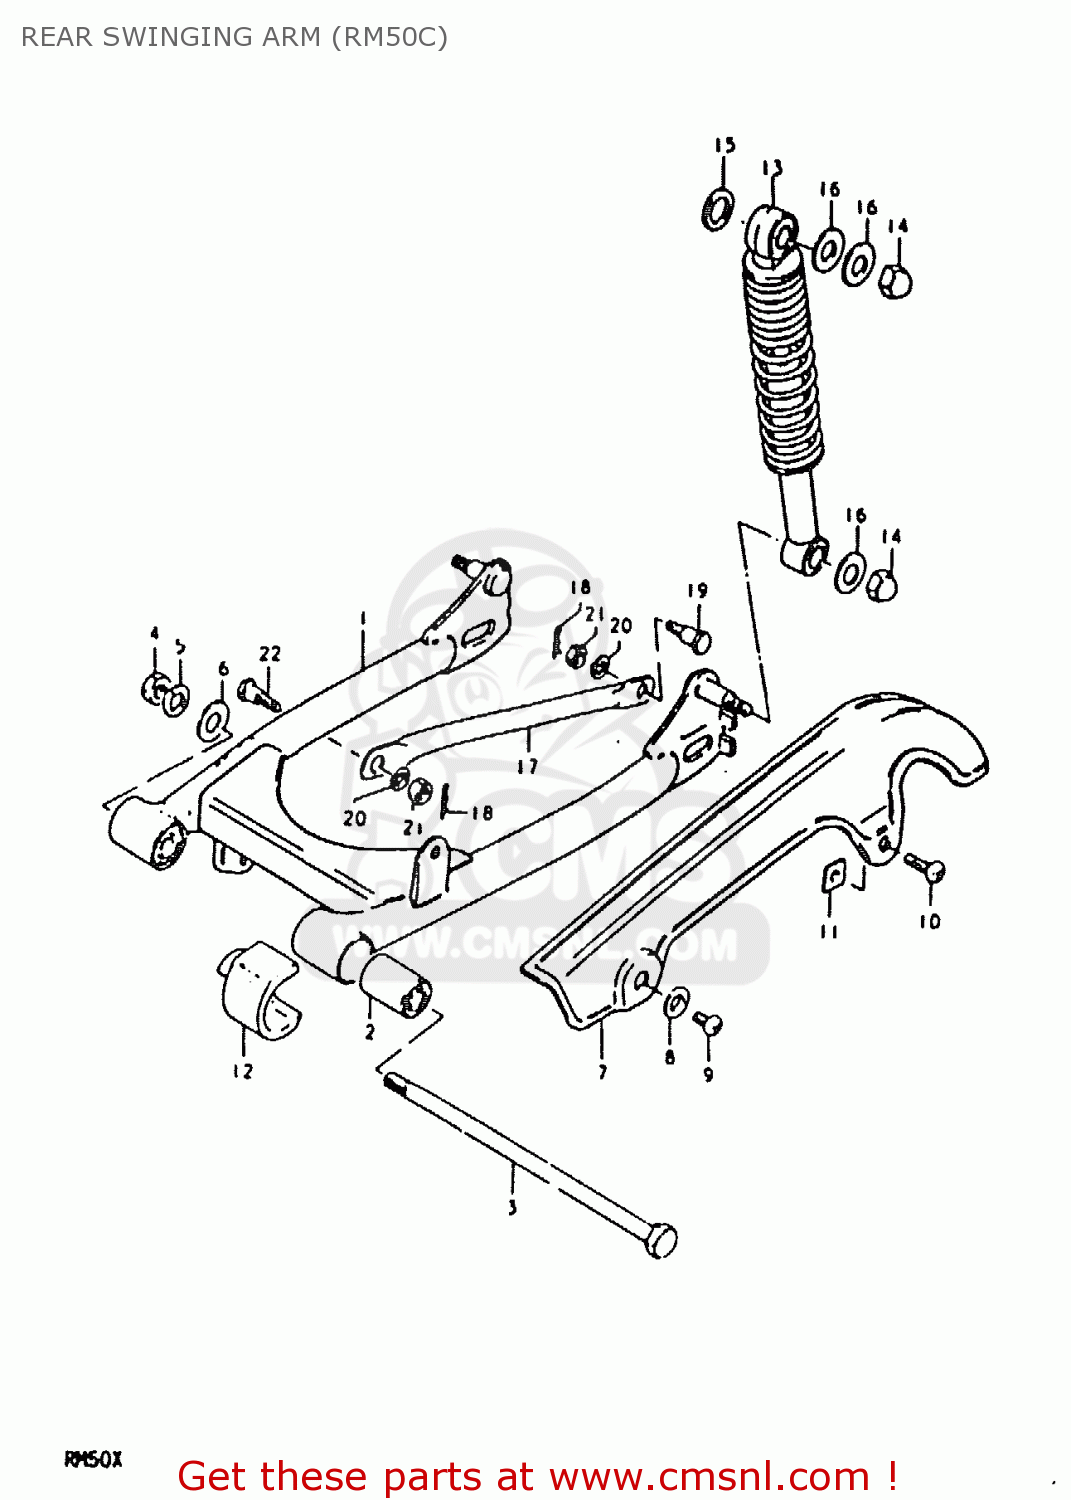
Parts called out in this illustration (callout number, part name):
1	SWING ARM ASSEMBLY,REAR
2	BUSH
3	SHAFT,REAR SWING ARM
4	NUT
5	LOCK WASHER
6	WASHER
7	CASE,CHAIN
8	WASHER
9	SCREW
10	SCREW 6X12
11	NUT,CHAIN CASE RR
12	BUFFER,CHAIN TOUCH DEFLECTOR
13	ABSORBER ASSEMBLY,REAR SHOCK
14	NUT, LOWER LH
15	WASHER
16	WASHER
17	TORQUE LINK,REAR
18	CLIP
19	BOLT(8X26.5)
20	LOCK WASHER
21	NUT
22	BOLT(8X22)
